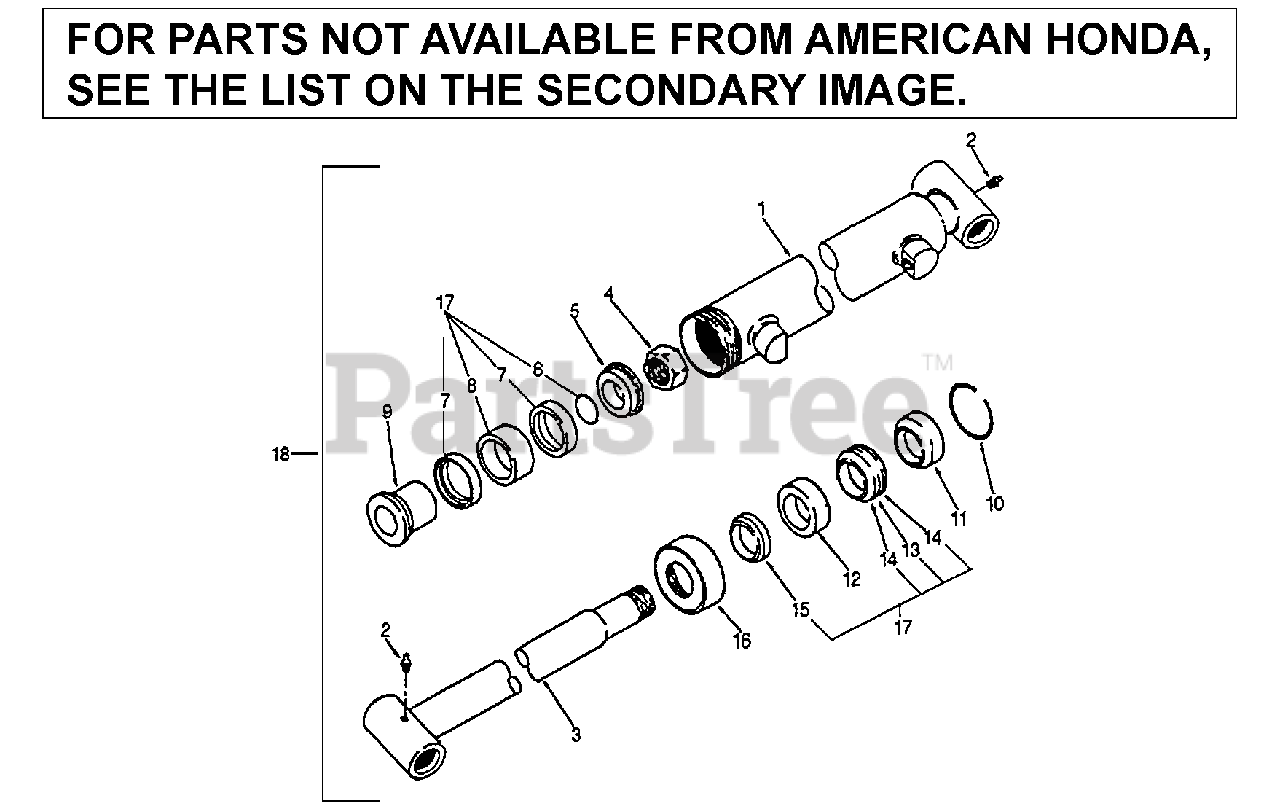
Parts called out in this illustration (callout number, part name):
1	BODY ASSY., BUCKET CYLINDER
2	FITTING, GREASE
3	ROD ASSY., BUCKET CYLINDER
4	LOCKNUT (5/8 - 18)
5	END, PISTON
9	PISTON, CYLINDER
10	WIRE, RETAINING
11	GUIDE, GASKET MALE
12	GUIDE, GASKET FEMALE
16	NUT, CARTRIDGE
17	SEAL KIT
18	CYLINDER ASSY., BUCKET
